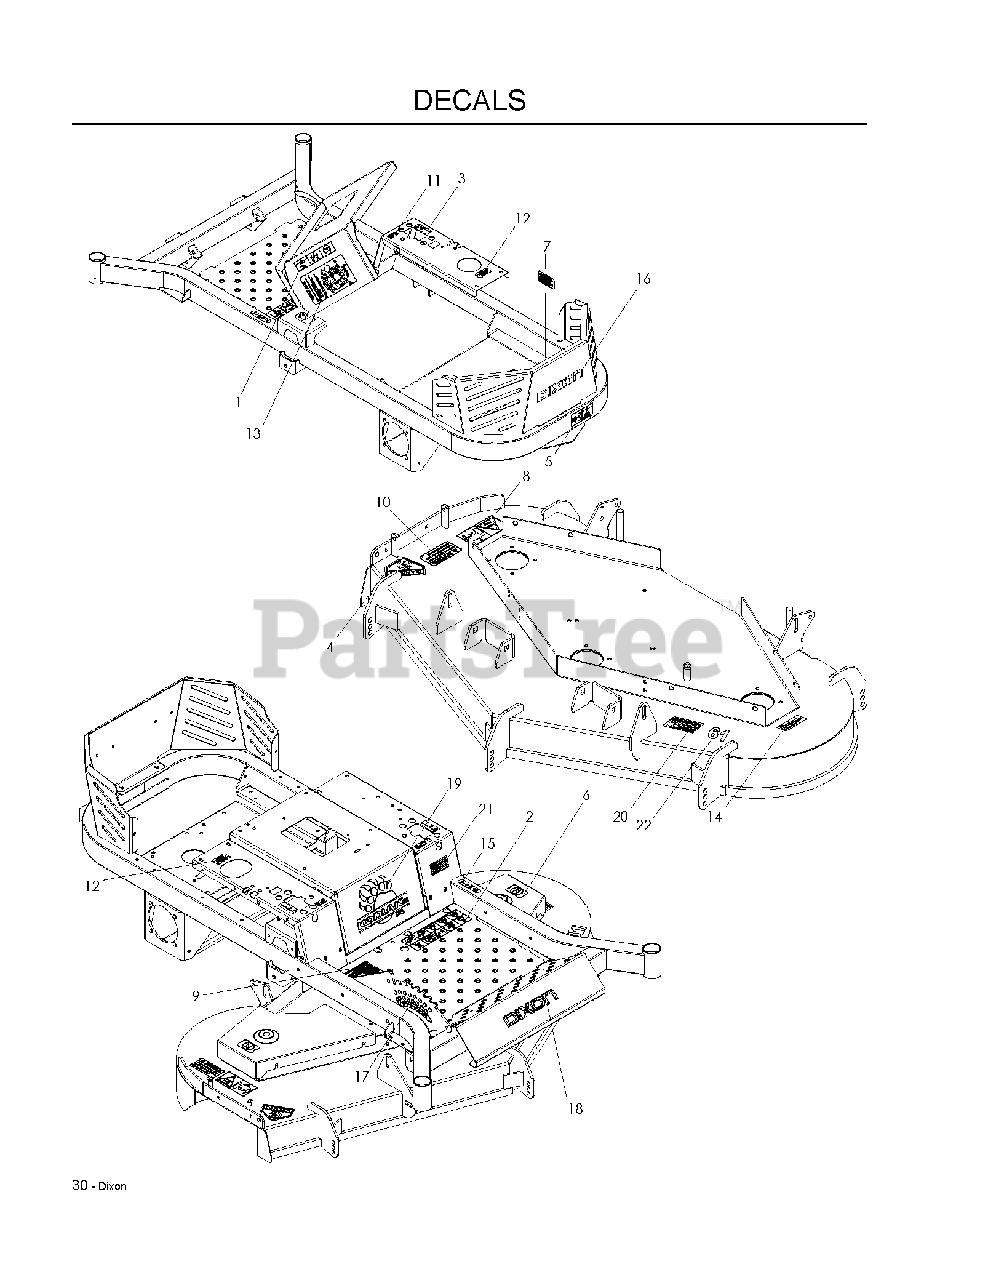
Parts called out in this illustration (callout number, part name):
1	DECAL, BATTERY
2	DECAL, WARNING
3	DECAL, MOTION CONTROL
4	DECAL, CPSC
5	DECAL, BELT DRIVE
6	DECAL, NO STEP
7	DECAL, PROP. 65
8	DECAL, EURO SEVERING
9	DECAL, WARNING
10	DECAL, CAUTION
11	DECAL, F.S.T.
12	DECAL, OIL TANK
13	DECAL, SERVICE
14	DECAL, FUSION
15	DECAL, PARK BRAKE
16	DECAL, DIXON LOGO FLAT
17	DECAL, HEIGHT 5"
18	DECAL, DIXON LOGO, DOMED
19	DECAL, KODIAK SE
20	DECAL, TRI-FORCE COMM
22	DECAL, 61
